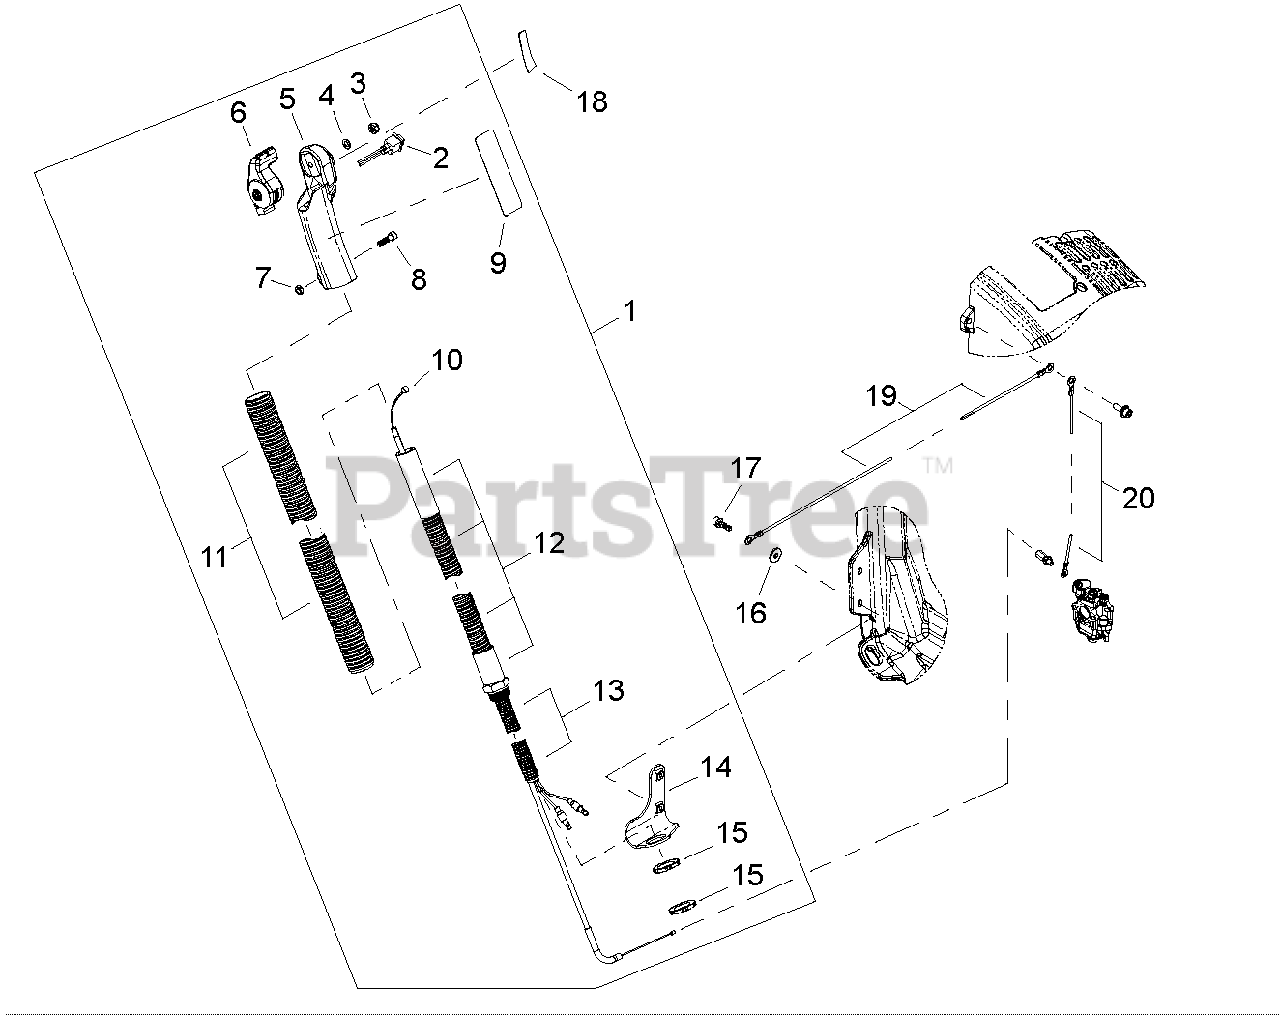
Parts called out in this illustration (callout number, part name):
1	THROTTLE CONTROL ASSY
2	IGNITION SWITCH ASSY
3	NUT - 5
4	WASHER - 5
5	GRIP
6	THROTTLE LEVER ASSY
7	NUT - 5
8	SCREW - 5X20
9	PLATE - GROUND
10	CABLE, THROTTLE
11	TUBE, PROTECTIVE
12	FLEX ARM
13	FLEX TUBE
14	BRACKET, MOUNTING
15	NUT - 21
16	COLLAR
17	SCREW - 5X18
18	LABEL - INSTRUCTION
19	LEAD - GROUND
20	LEAD - ANTI-STATIC - 110mm
